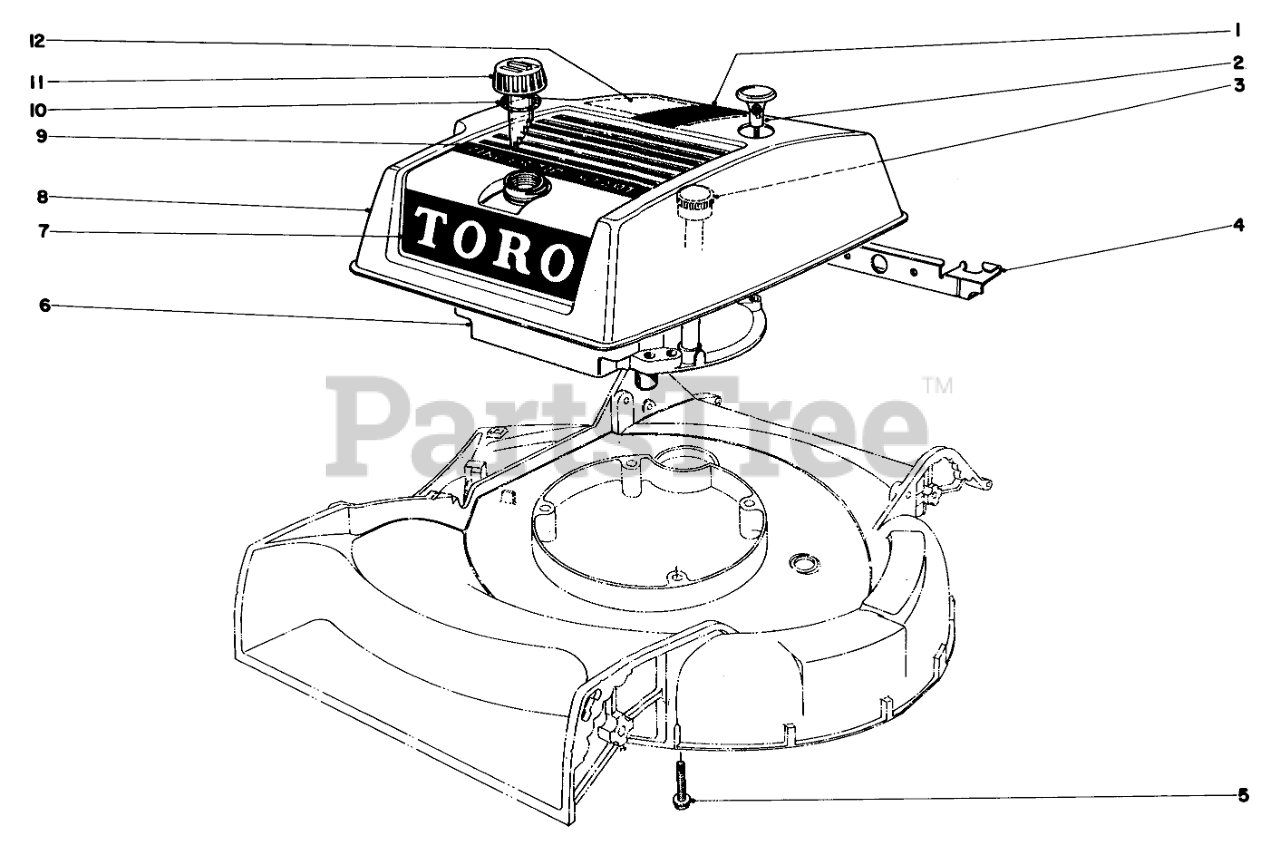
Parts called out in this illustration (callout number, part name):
1	Decal
2	Rope Handle
3	Dip Stick
4	Shroud Bracket
5	3/8-16 X 2-3/4 CAPSCR
6	Engine
7	Decal-Toro
8	Shroud
9	Decal
10	Gasket
11	Gas Cap (Incl. Ref. No. 10)
12	Decal-Maintenance
